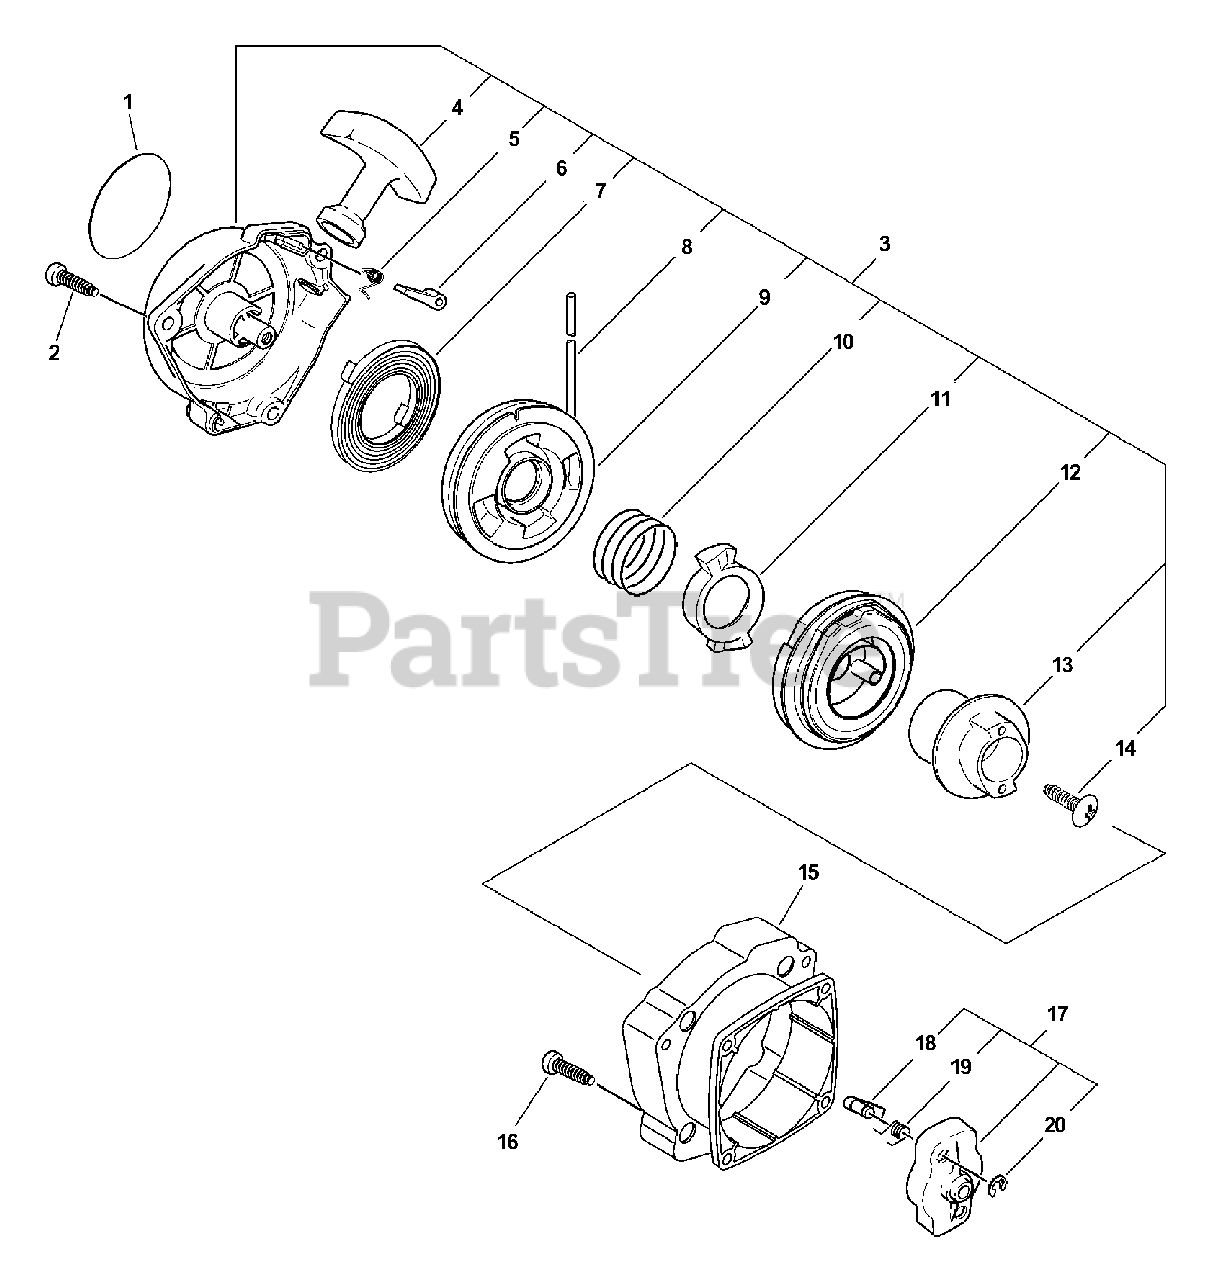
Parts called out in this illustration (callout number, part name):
1	LABEL, EZR
2	SCREW, TAPPING 5×20
3	STARTER ASSY
4	GRIP, STARTER
6	PAWL, STARTER
7	SPRING, RECOIL
8	ROPE, STARTER
9	PULLEY, STARTER
10	SPRING, RETURN
11	PAWL, STARTER
12	SPRING ASSY
13	PLATE, CAM
15	BODY, STARTER PAWL
16	BOLT 4×16
17	STARTER PAWL ASSY
18	PAWL, STARTER
19	SPRING, RETURN
20	E-RING 4
